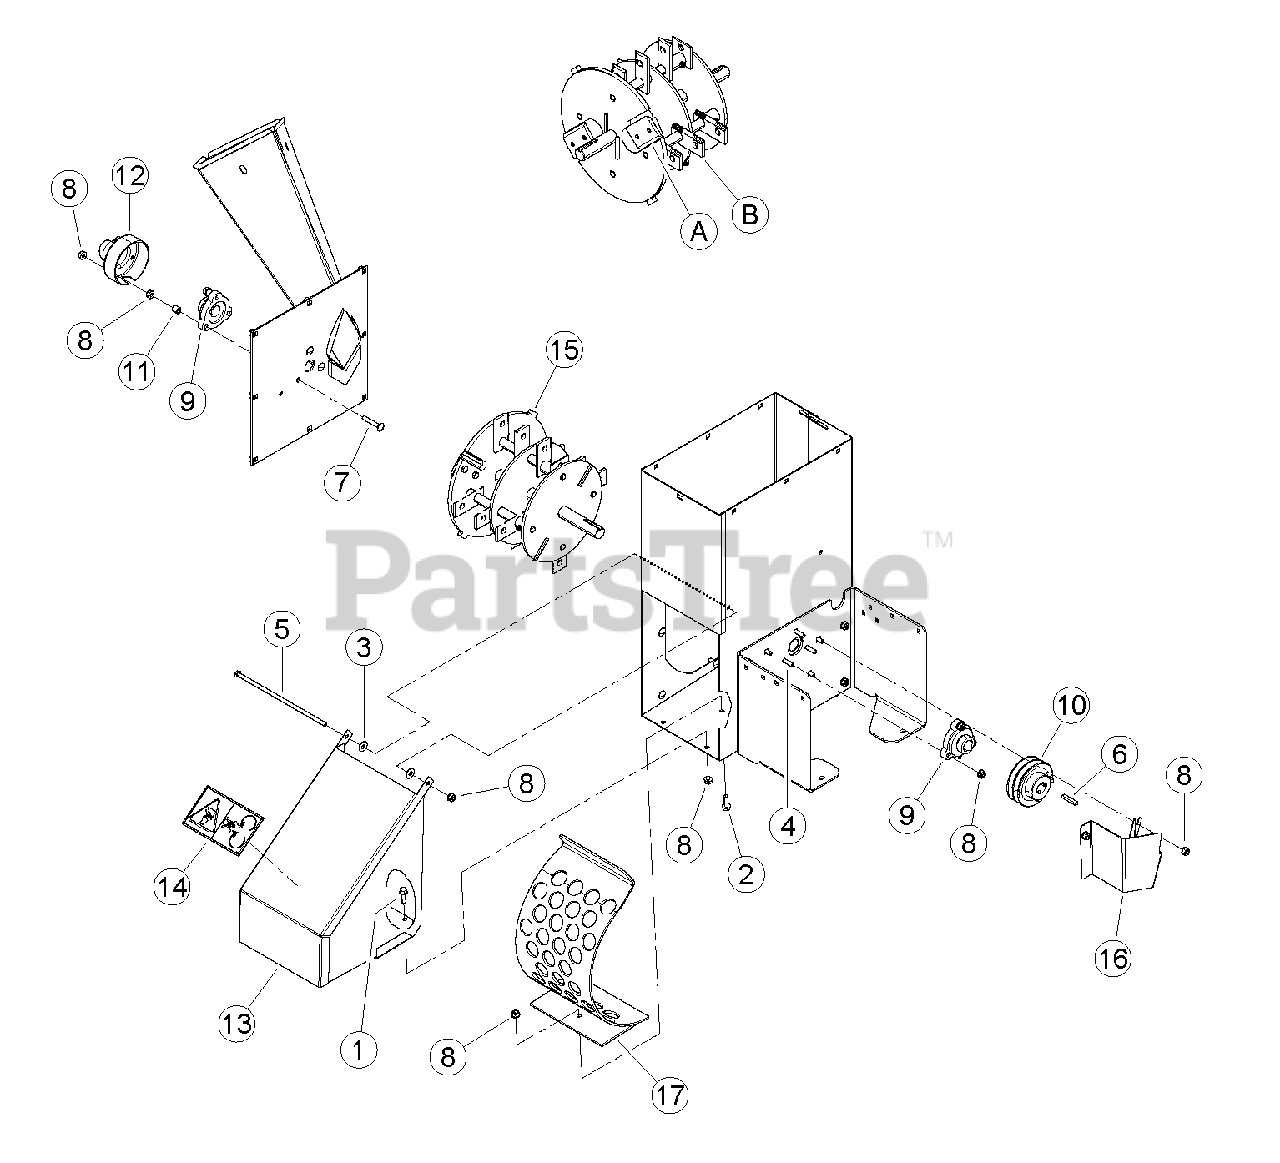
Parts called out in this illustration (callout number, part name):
1	BOLT, 5/16 X 3/4 FLANGE NC
2	BOLT, 5/16 X 1 FLANGE NC
3	WASHER, 5/16 FLAT ZP
4	BOLT, 5/16 X 1-1/4 CRG GR5 ZP
5	BOLT, 5/16 X 10 HEX GR5 NC ZP
6	KEY, 1/4 SQUARE X 1-1/2 LONG PLAIN
7	BOLT, 5/16 X 2 CRG GR5 NC ZP
8	NUT, 5/16-18 NYLOCK-FLANGE
9	BEARING, 1" FLUSHMOUNT CAST W/COLLAR
10	PULLEY, 4X1 2A GROOVE
11	SPACER, .54 OD X .50 LG
12	CAP, ROTOR SHAFT END CAP
13	ASSEMBLY, WIDE EUROPEAN DISCHARGE
14	DECAL, BLADE DANGER ISO
15	ASSEMBLY, ROTOR
16	SHIELD, LOWER
17	WELDMENT, WIDE COARSE TAPERED
A	KIT, CHIPPER BLADE
B	KIT, 3" SHREDDER KNIVES (ALL WIDE BODY MODELS)
